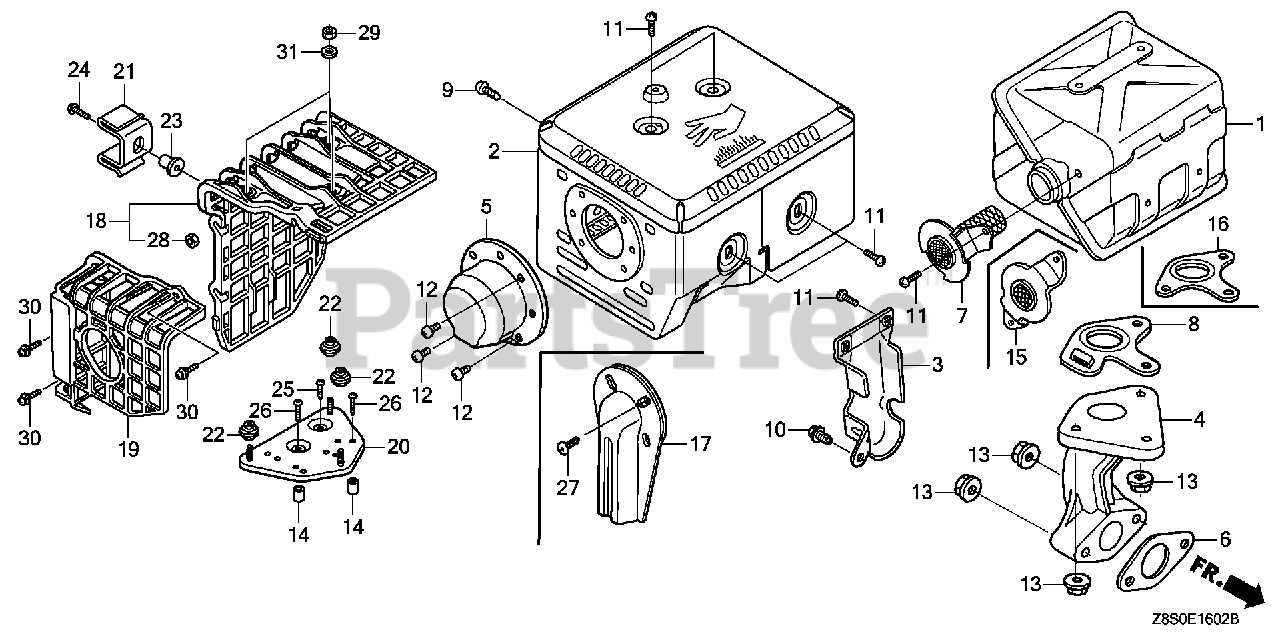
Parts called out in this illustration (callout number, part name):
1	MUFFLER
2	PROTECTOR, MUFFLER
3	PROTECTOR, EX. PIPE
5	CAP, MUFFLER
6	GASKET, EX. PIPE
7	ARRESTER, SPARK
8	GASKET, MUFFLER (ARRESTER) (NIPPON LEAKLESS)
9	SCREW, TAPPING (6X10)
10	BOLT, FLANGE (6X12) (CT200)
11	SCREW, TAPPING (5X8)
12	SCREW, TAPPING (4X6)
13	NUT, FLANGE (8MM)
15	FLANGE, BAFFLE
16	GASKET, MUFFLER (NIPPON LEAKLESS)
16	GASKET, MUFFLER (THAI LEAKLESS)
